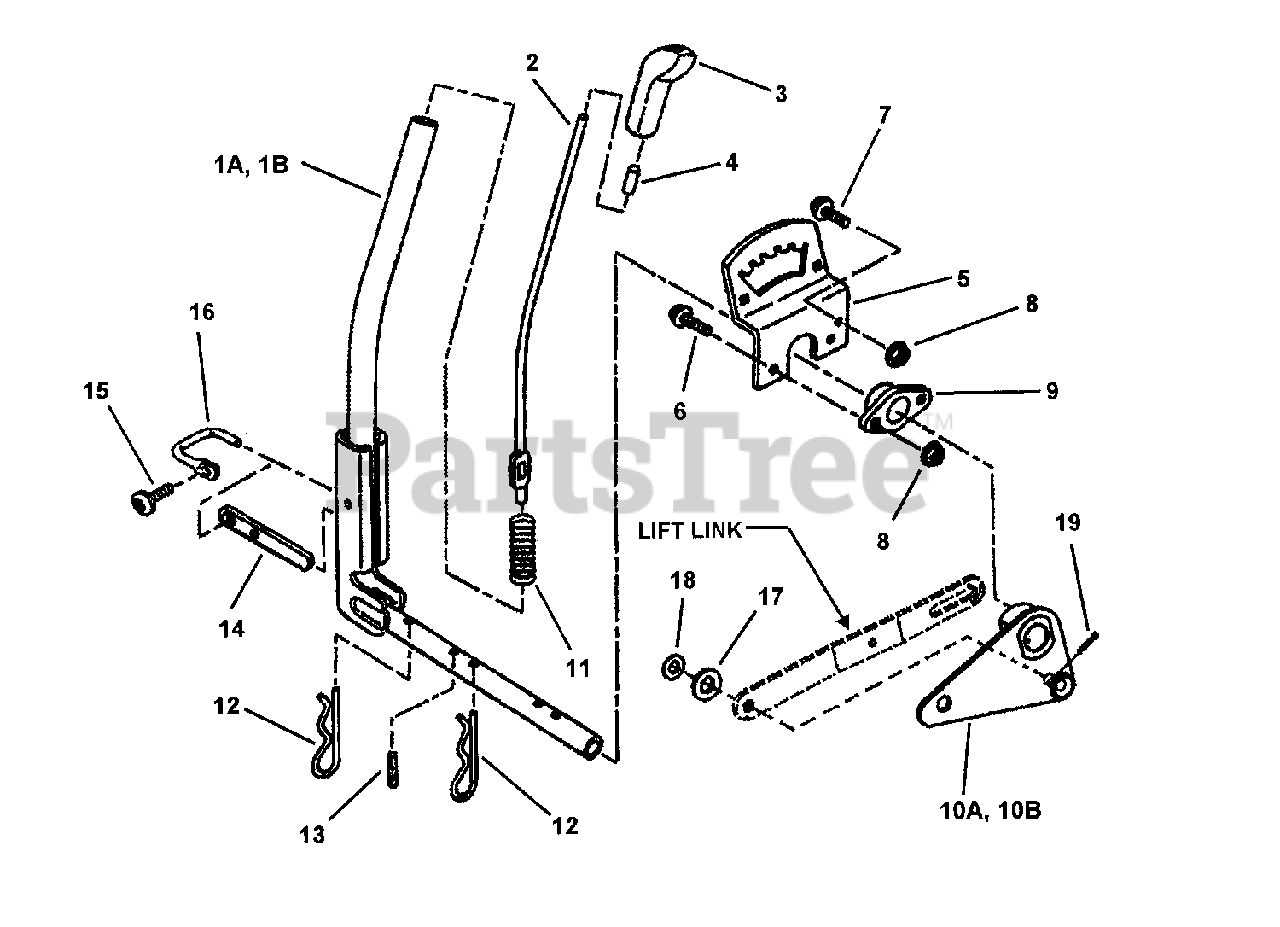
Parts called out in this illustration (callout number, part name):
1A	WELDMENT, Lift Lever-33/42
2	ROD, Lift Lever
3	KNOB, Lift Handle
4	CAP, Lift Rod
5	QUADRANT, Lift Lever
6	SCREW, 5/16-18 x 7/8" Truss Head (Torx)
7	SCREW, 5/16-18 x 5/8" Truss Head (Torx)
8	NUT, 5/16-18 Hex Flange Lock, GR5
9	PIVOT, Lift Lever
10A	WELDMENT, Bellcrank, 30/38/42
11	SPRING, Latch Detent
12	COTTER HAIR PIN, 2-5/8"
13	PIN, Dowel, .25 x 1.12
14	DETENT, Lift Lever
15	SCREW, 1/4-20 x 5/8 Pan Head Self-Tap (Torx)
16	PIVOT, Latch Detent
17	WASHER, .531 x 1.062 x .121 Flat SAE
18	WASHER, 3/8" Flat SAE
19	PIN, 3/32 x 3/4" Cotter
